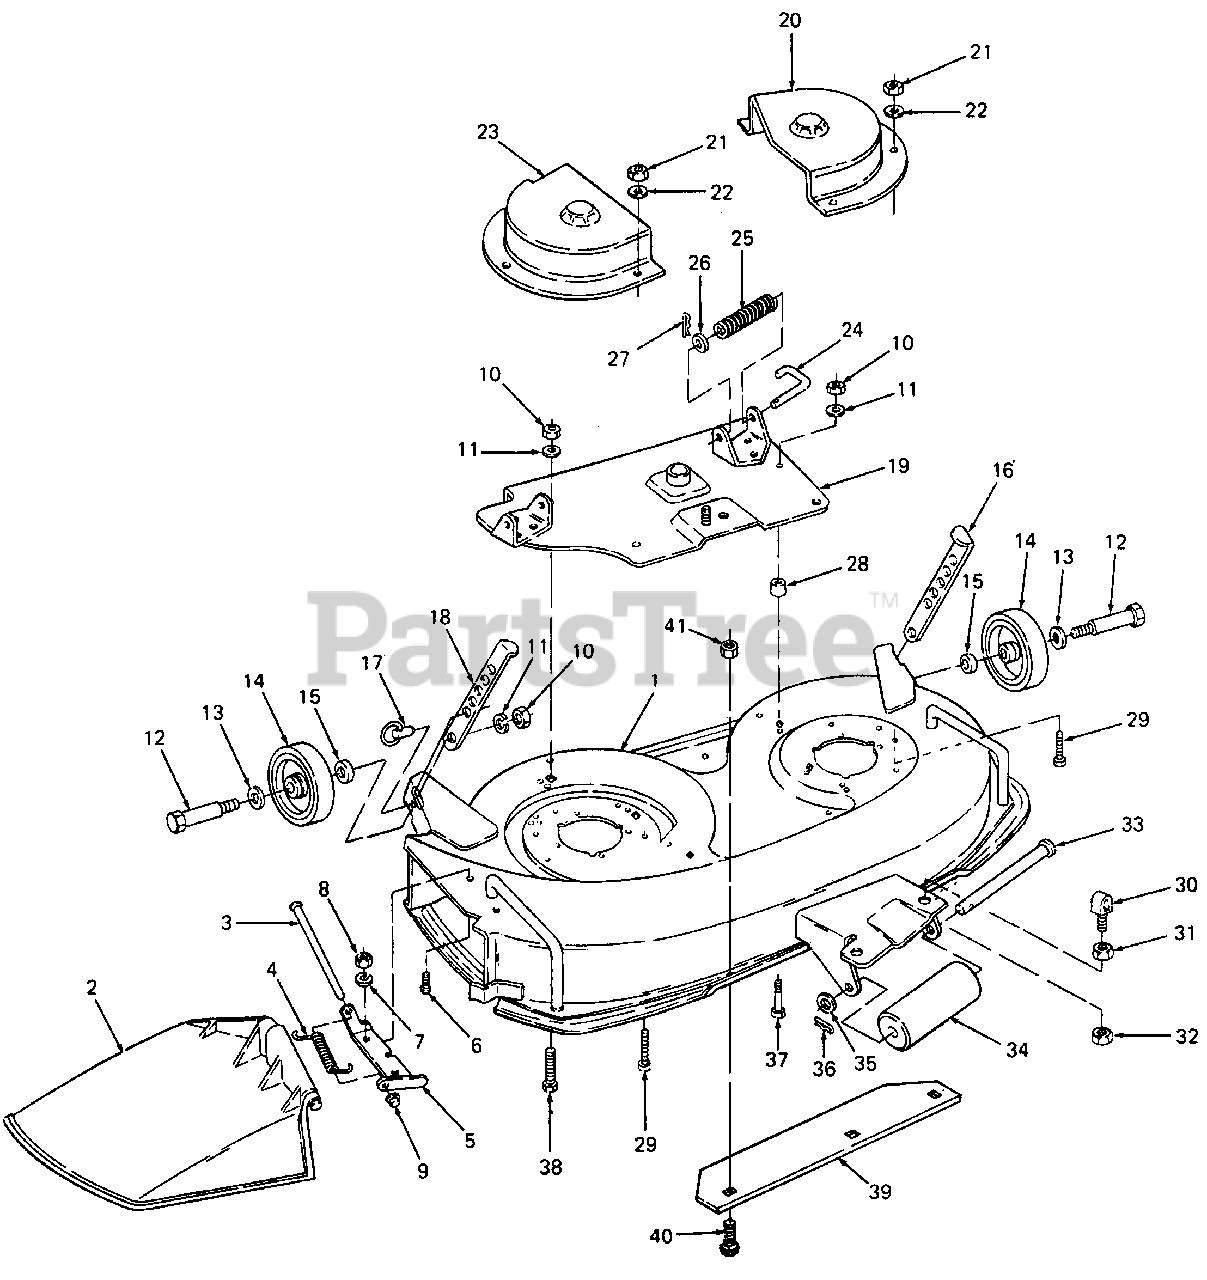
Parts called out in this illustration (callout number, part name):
2	Chute Kit w/Graphic
3	Pin, Hinge, .25 Dia X 6.75 Lg
4	Spring, Torsion
5	Bracket, Hinge Mtg
6	Screw, Truss Machine, 1/4-20 X .75 Lg, Phillips
7	Washer, Lock, 1/4 Dia
8	Nut, Hex Jam, 1/4-20
9	Cap, Speed Nut
10	Nut, Hex, 3/8-16 GR5
11	Washer, Lock, 3/8 Dia
12	Bolt, Shld, .50 Dia X 1.62 Lg X 3/8-16
13	Washer, Flat, .515 ID X 1.12 OD X .100 Thk
14	Wheel, Gauge, 5" Dia
15	Spacer, .385 X .075 X .75 Lg
16	Bar, Height Adjustment LH
17	Pin, Clevis w/Detent Ball
18	Bar, Height Adjustment RH
19	Adapter Plate Assy
20	Cover, Belt LH
21	Nut, Hex, 5/16-18 GR5
22	Washer, Flat, .34 X .68 X .06 Thk
23	Cover, Belt RH
24	Pin, Mower Support
25	Spring, Compression
26	Washer, Flat, .531 X .930 X .050 Thk
27	Pin, Spirol Spring, 3/16 Dia X .75 Lg
28	Spacer, .390/.400 ID X .75 OD X .44 Lg
29	Screw, Hex Head Cutting, 5/16-18 X .75 Lg
30	Hanger, Front Mower Support
31	Nut, Hex Jam, 5/8-11 GR5
32	Nut, Hex Insert Top Lock, 5/8-11 GR5
33	Pin, Clevis, 1/2 Dia X 7.0 Lg
34	Roller, Front
35	Washer, Flat, .510 X 1.0 X .06 Thk
36	Pin, Cotter, 3/16 Dia X 1.0 Lg
37	Screw, Hex Cap, 3/8-16 X 1.25 Lg GR5
38	Bolt, Short Neck Carr, 3/8-16 X .75 Lg GR5
41	Nut, Sems, 1/4-20
